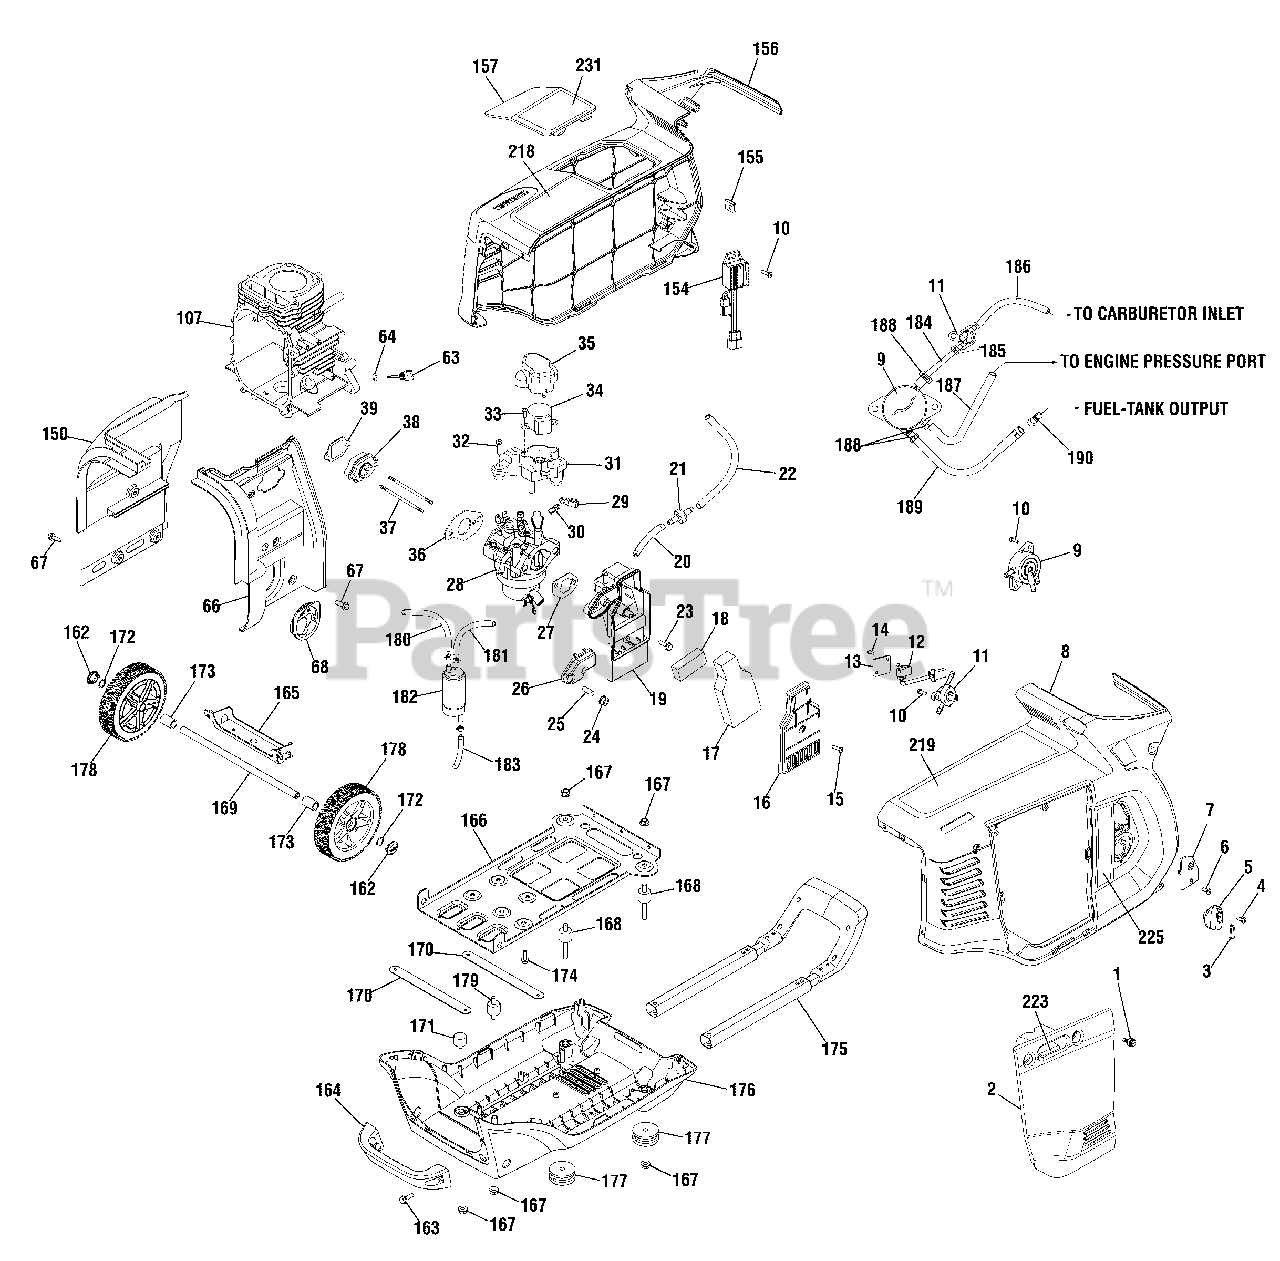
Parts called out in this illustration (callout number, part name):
4	SCREW
6	SCREW
9	PUMP-FUEL
10	SCREW
13	COVER-SWITCH
14	SCREW
16	COVER-AIR CLEANER
17	FILTER-A/C FOAM
18	FILTER-A/C FOAM
19	BASE-AIR CLEANER
23	BOLT-M5 x 12
24	NUT
25	SLEEVE
26	COVER-AIR CLEANER
27	GASKET-AIR CLEANER
29	ROD-THROTTLE
30	SPRING
32	SCREW
33	SCREW
34	MOTOR-STEPPER
66	DEFLECTOR
67	BOLT-M6 x 12
68	SEAL-RUBBER
107	CRANKCASE
150	DEFLECTOR
154	REGULATOR-VOLTAGE
155	NUT
157	COVER-SPARK PLUG
163	BOLT-M6 x 25
167	NUT-FLANGE M8
168	MOUNT-VIBRATION
171	MOUNT-VIBRATION
172	CLIP
174	BOLT-M8 x 16
177	MOUNT-VIBRATION
179	MOUNT-VIBRATION
185	CLAMP
188	CLAMP
